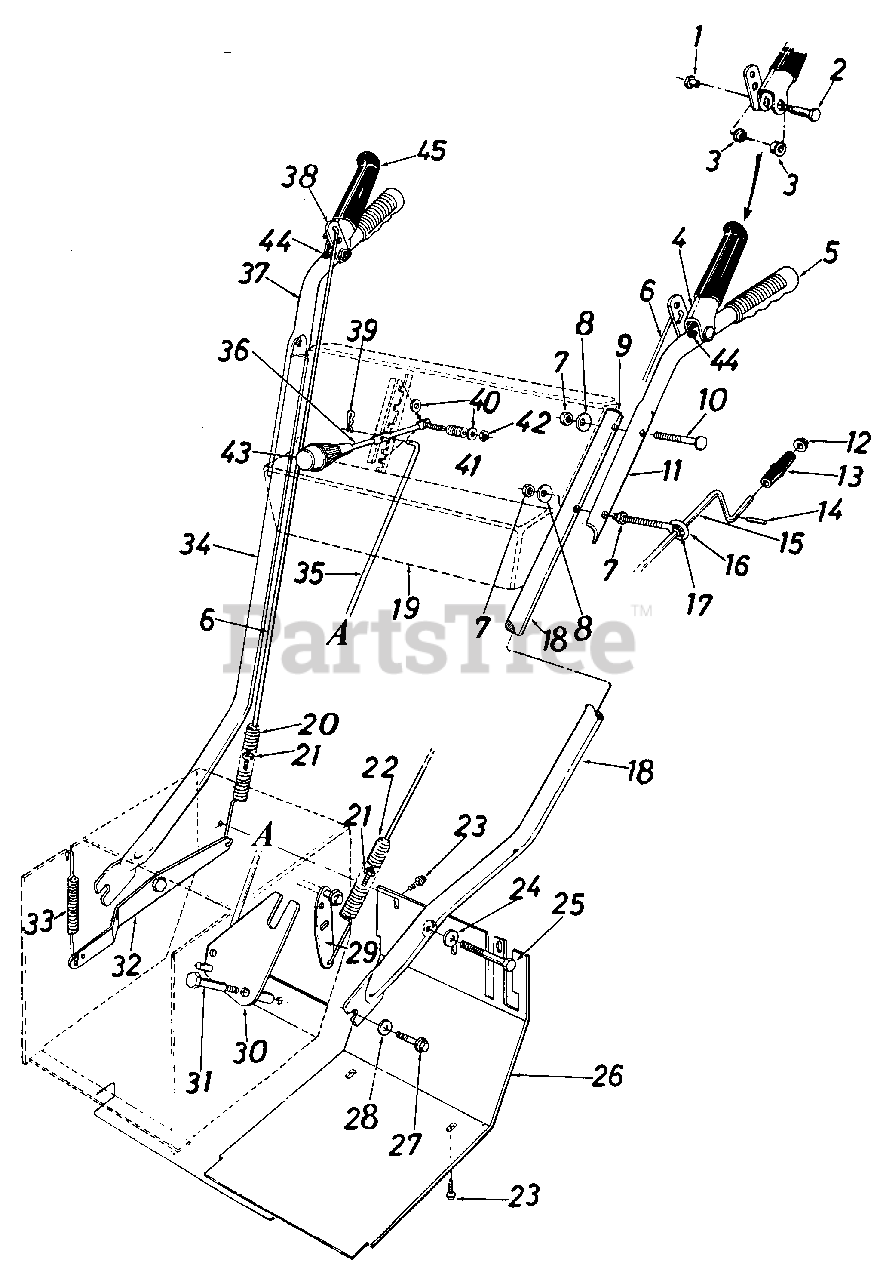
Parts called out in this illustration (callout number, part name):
1	NUT-SHLD
2	SCREW-SHLD .374 DIA X1.530
3	BEARING-FLANGE
4	GRIP ASSY-LH CLUTCH 2-STG S/T MTD
5	GRIP-BLACK
6	ROD-LOCKOUT STIC
7	NUT-HEX 5/16-18
8	WASHER-BELL .337 X .867 X .057
10	BOLT-CARRIAGE 5/16-18 X 2.00
11	HANDLE-FOLDING-LH PAINTED
13	KNOB-CHUTE CRANK
14	PIN-ROLL 1/18 DIA
15	CRANK ASSY-CHUTE
17	BUSHING-.380 ID
18	HANDLE-LOWER-LH PAINTED
19	PANEL ASSY-HANDLE
20	SPRING-EXTENSION
21	NUT-INS LOCK 1/4-20
23	SCREW-HEX WASH SF TAPP
24	WASHER-BELL .400 ID X .88 X .060
25	SCREW-HEX 3/8-16 X 2.00
26	COVER-FRAME
27	SCREW-PILOT 3/8-16 X .88
28	WASHER-BELL .400 ID X .88 X .060
29	BRACKET ASSY-DR CLUTCH
32	BRACKET-AUG CLUTCH
33	SPRING-EXTENSION
34	HANDLE-LOWER-RH PAINTED
36	HANDLE-SHIFT
39	PIN-INTERN COT-5/16 DIA
40	WASHER-FL-.344 X .62
41	SPRING-COMPRESSION
42	NUT-HEX INS L-5/16-18
44	CAP-PUSH
45	VINYL-PLASTIC
